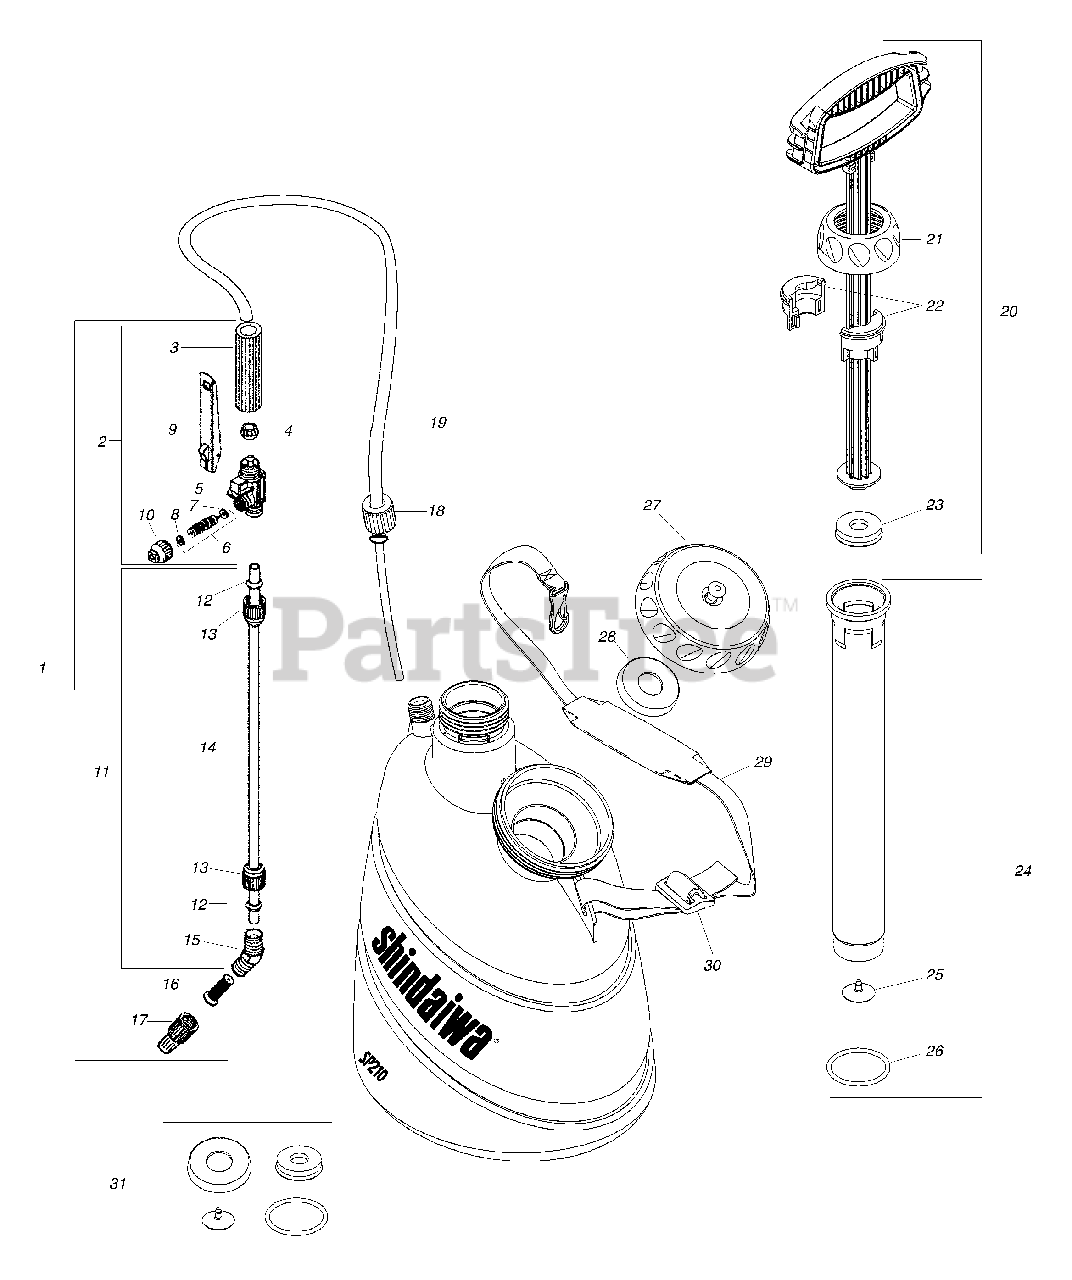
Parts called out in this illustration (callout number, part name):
1	SPRAY WAND ASSY
2	TRIGGER VALVE ASSY
3	HANDLE, TRIGGER VALVE
5	BODY, TRIGGER VALVE
6	TRIGGER VALVE NEEDLE ASSY
7	SEAL - LOWER
8	SEAL - UPPER
9	TRIGGER
10	TRIGGER VALVE CAP ASSY
11	SPRAY TUBE ASSY
12	CONE PACKING
13	SCREW
14	SPRAY WAND TUBE
15	ELBOW
16	FILTER, NOZZLE
17	ADJUSTABLE CONE NOZZLE
18	NUT - 20X1.5
19	HOSE/DIP TUBE ASSY
20	PUMP HANDLE ASSY
21	CYLINDER CAP
22	BUSHING
23	CUP, PISTON
24	PUMP TUBE ASSY
25	DIAPHRAGM VALVE, VITON(R)
25	VALVE, DIAPHRAGM
26	O-RING
27	LID, TANK
28	GASKET
28	GASKET, TANK LID - VITON
29	STRAP ASSY
30	BUCKLE, STRAP - LOWER
31	SEAL KIT
